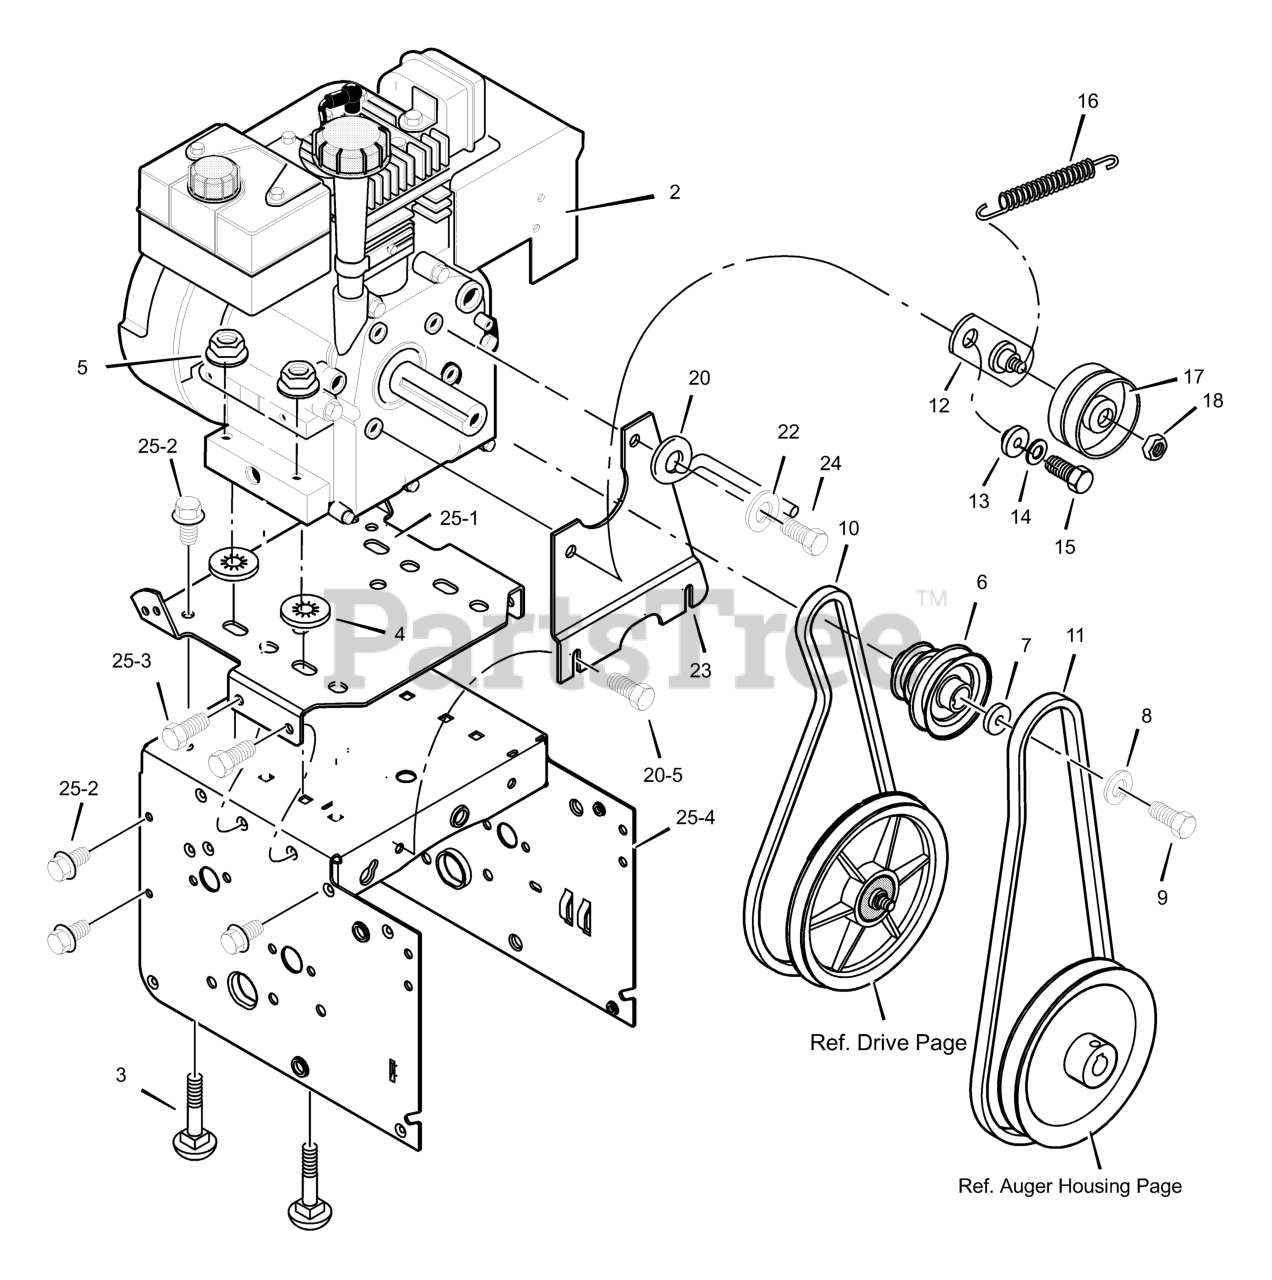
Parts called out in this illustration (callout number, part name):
2	ENGINE
3	BOLT, CARRIAGE 5/16-18
4	RETAINER, PUSH
5	NUT, HEX 5/16-18
6	PULLEY, ENGINE
7	WASHER
8	WASHER .38ID
9	SCREW, 3/8-24 x 1.00
10	BELT, DRIVE V 3L
11	BELT, AUGER V 4L
12	BRACKET ASSEMBLY, IDLER
13	BUSHING, IDLER BRACKET
14	WASHER, SPLIT
15	SCREW 5/16-24 X 1.00
16	SPRING, IDLER TRACTION DRIVE
17	PULLEY, IDLER
18	NUT, JAM 3/8-16
20	GUIDE, BELT
22	WASHER, SPTLK .31X.58X.08
23	PLATE, ANTI VIBRATION
24	SCREW, 5/16-24 x 1.00
25	FRAME ASSEMBLY
25-1	PLATE, ENGINE MOUNT
25-2	SCREW, TAP 1/4-20 X .63
25-3	SCREW, TAP 5/16-18 X .50
25-4	FRAME, MOTOR BOX
